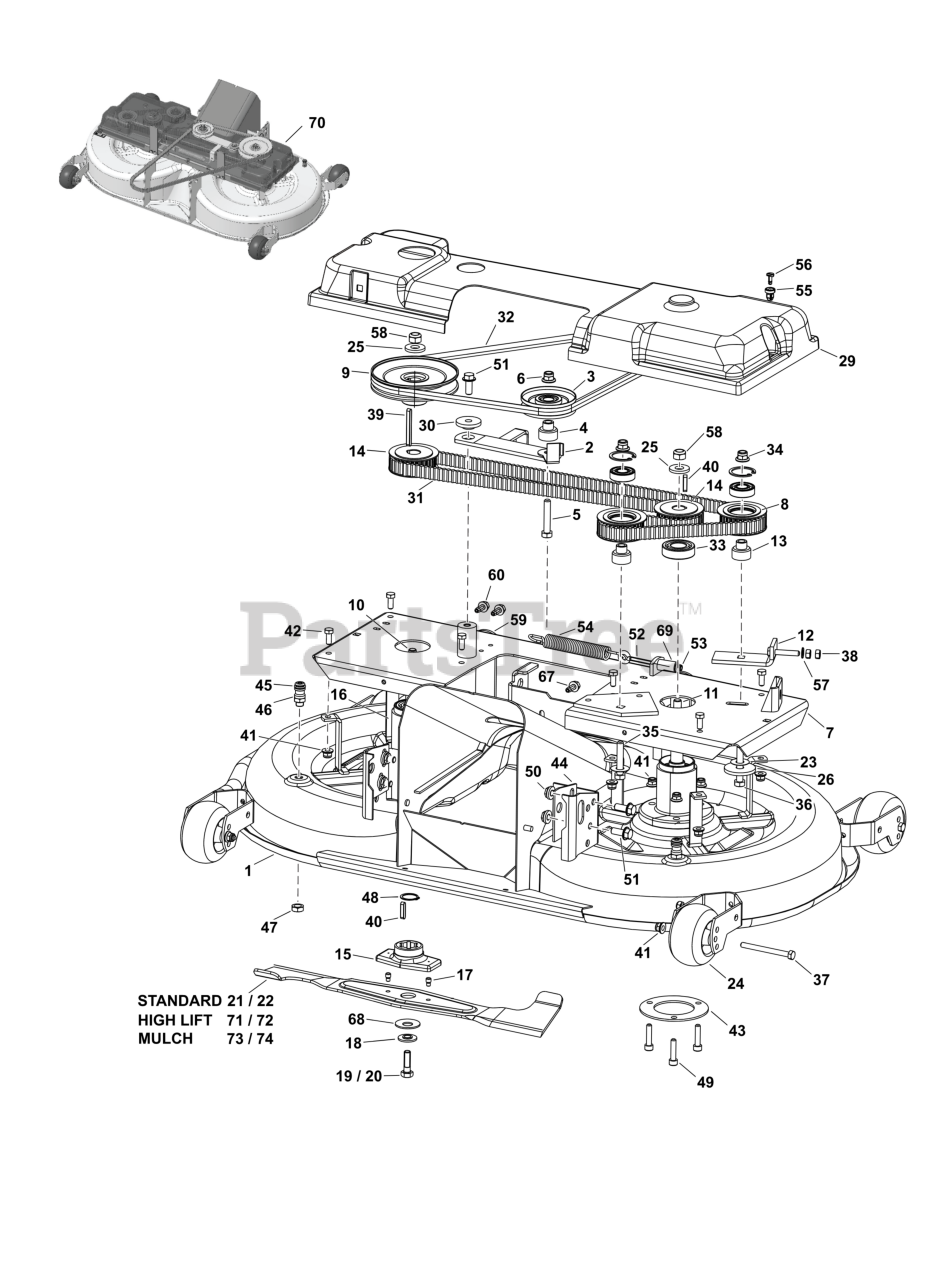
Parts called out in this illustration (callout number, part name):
12	FOOT, Mounting
17	STUD ( 100 PCS )
21	BLADE, Left, 102cm
22	BLADE, Right, 102cm
29	COVER, Belt
43	PLATE, Reinforcement
45	CONNECTOR
71	BLADE, High Lift, Left, 102cm
72	BLADE, High Lift, Right, 102cm
73	BLADE, Mulch, Left, 102cm
74	BLADE, Mulch, Right, 102cm
